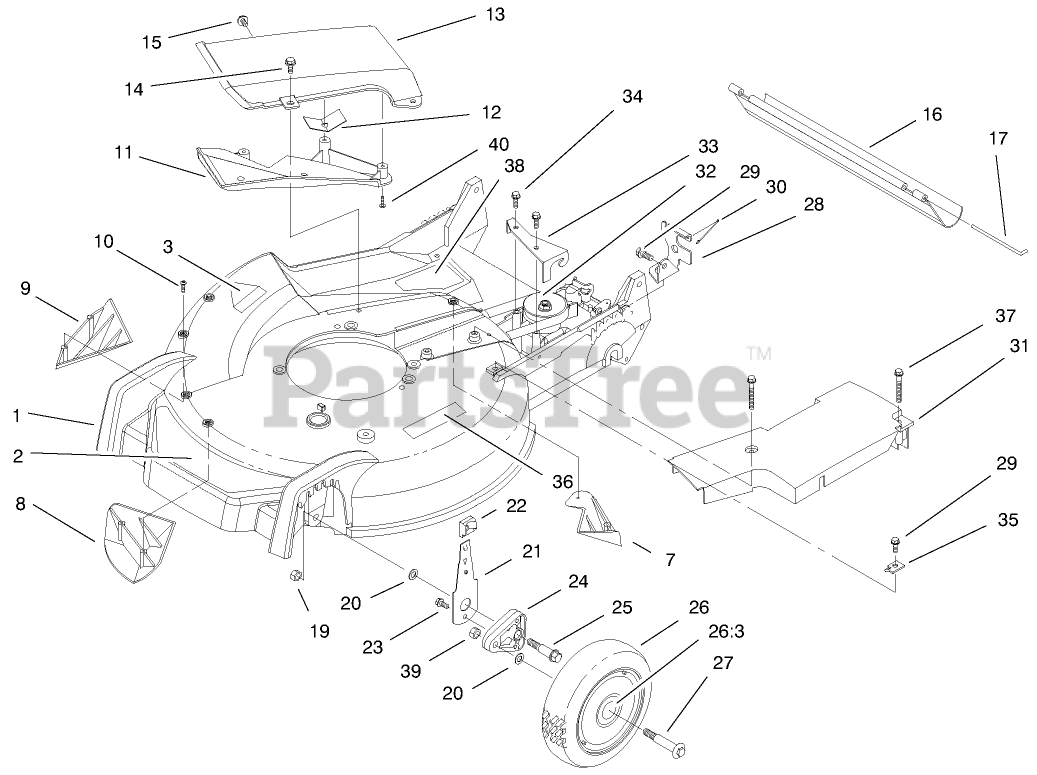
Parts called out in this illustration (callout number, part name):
1	HOUSING
2	DECAL - DECK
3	DECAL-DANGER
7	KICKER-REAR
8	KICKER-FRONT
9	KICKER-RH
10	SCREW-PPH
11	Deflector-Recycler
12	Guard-Cover
14	SCREW-HWH
15	SCREW AND WASHER ASM
17	ROD-SHIELD
19	NUT-LOCK
20	WASHER
21	FRONT SPRING ARM ASM
22	KNOB-ARM
23	SCREW-HWH
24	ARM-PIVOT, FRONT
25	BOLT-SHOULDER
26	WHEEL ASM
26:3	BUSHING
27	BOLT-SHOULDER
29	SCREW-HWHTF
30	RETAINER-CABLE
32	GEARCASE ASM
34	SCREW-HWHTF
35	CLAMP-CABLE
37	SCREW-HWH
38	DECAL - DANGER
39	LOCKNUT
40	Screw-PPH
